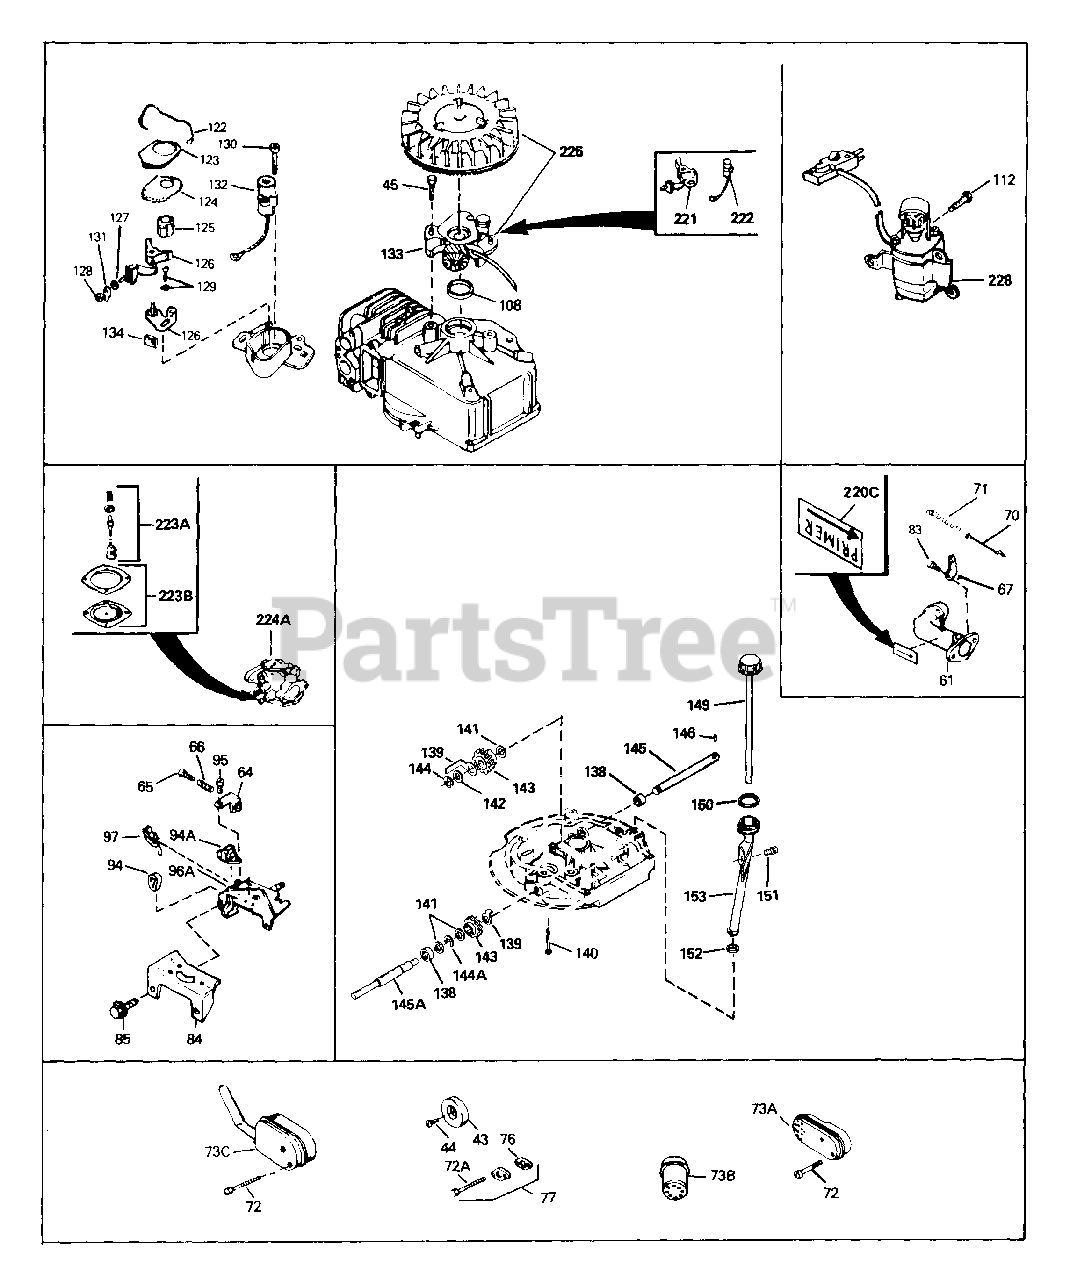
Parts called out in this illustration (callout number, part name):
45	Screw, Hex hd. Sems, 1/4-20 x 5/8
61	Pipe, Intake
67	Lever, Speed adjusting
70	Link, Governor spring
71	Spring, Governor
72	Screw, Hex hd., 1/4-20 x 2-3/8
72	Screw, Hex hd., 1/4-20 x 2-1/4
72	Screw, Hex hd., 1/4-20 x 2-3/4
72	Screw, Hex hd., 1/4-20 x 2-1/2
72A	Screw, Hex washer hd. Sems, 1/4-20 x 1/2
76	Gasket, Exhaust
77	Muffler Adapter Kit
83	Screw, Hex hd., 1/4-28 x 7/8
97	Terminal Assy.
108	Gasket, Stator
149	Dipstick, Oil (Twist Lock)
150	"O" Ring
151	Screw, Hex washer hd. shakeproof, 10- 32 x
152	Gasket, Oil fill tube
152	"O" Ring (.612 I.D. x .812 O.D. x .10 3
153	Tube, Oil fill (Plastic)
221	Contact Assy., Breaker
222	Condenser
225	Magneto, Tecumseh (w/ring gear)
